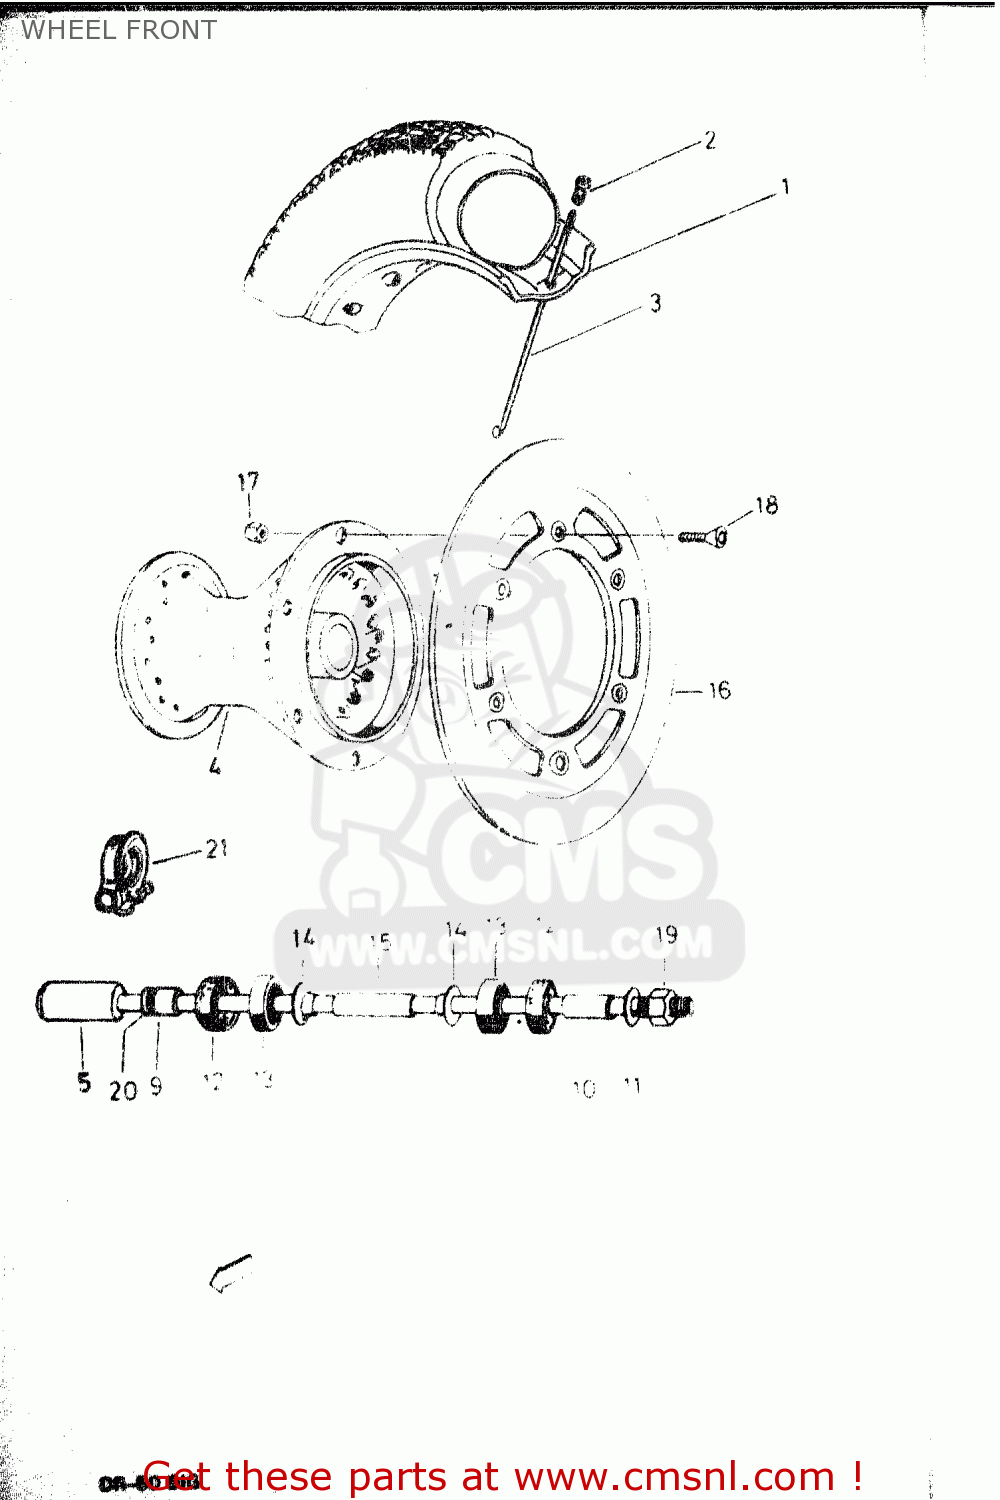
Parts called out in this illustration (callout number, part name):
1	RIM, FRONT WHEEL (1.35X21)
2	NIPPLE
3	SPOKE 2.9X242
4	HUB, FRONT WHEEL
5	AXLE, FRONT
9	SPACER 20X12X15,5
10	SPACER 20X12X31
11	WASHER B12 DIN 125
12	OIL SEAL (32X20X4)
13	BEARING
14	SPECIAL SHAPE WASHER
15	SPACER
16	DISK, FRONT BRAKE
17	NUT M6 DIN 985
18	SCREW M6X20 DIN 7991
19	NUT
20	SPACER 20X12X4
21	GEAR,SPEEDOMET
